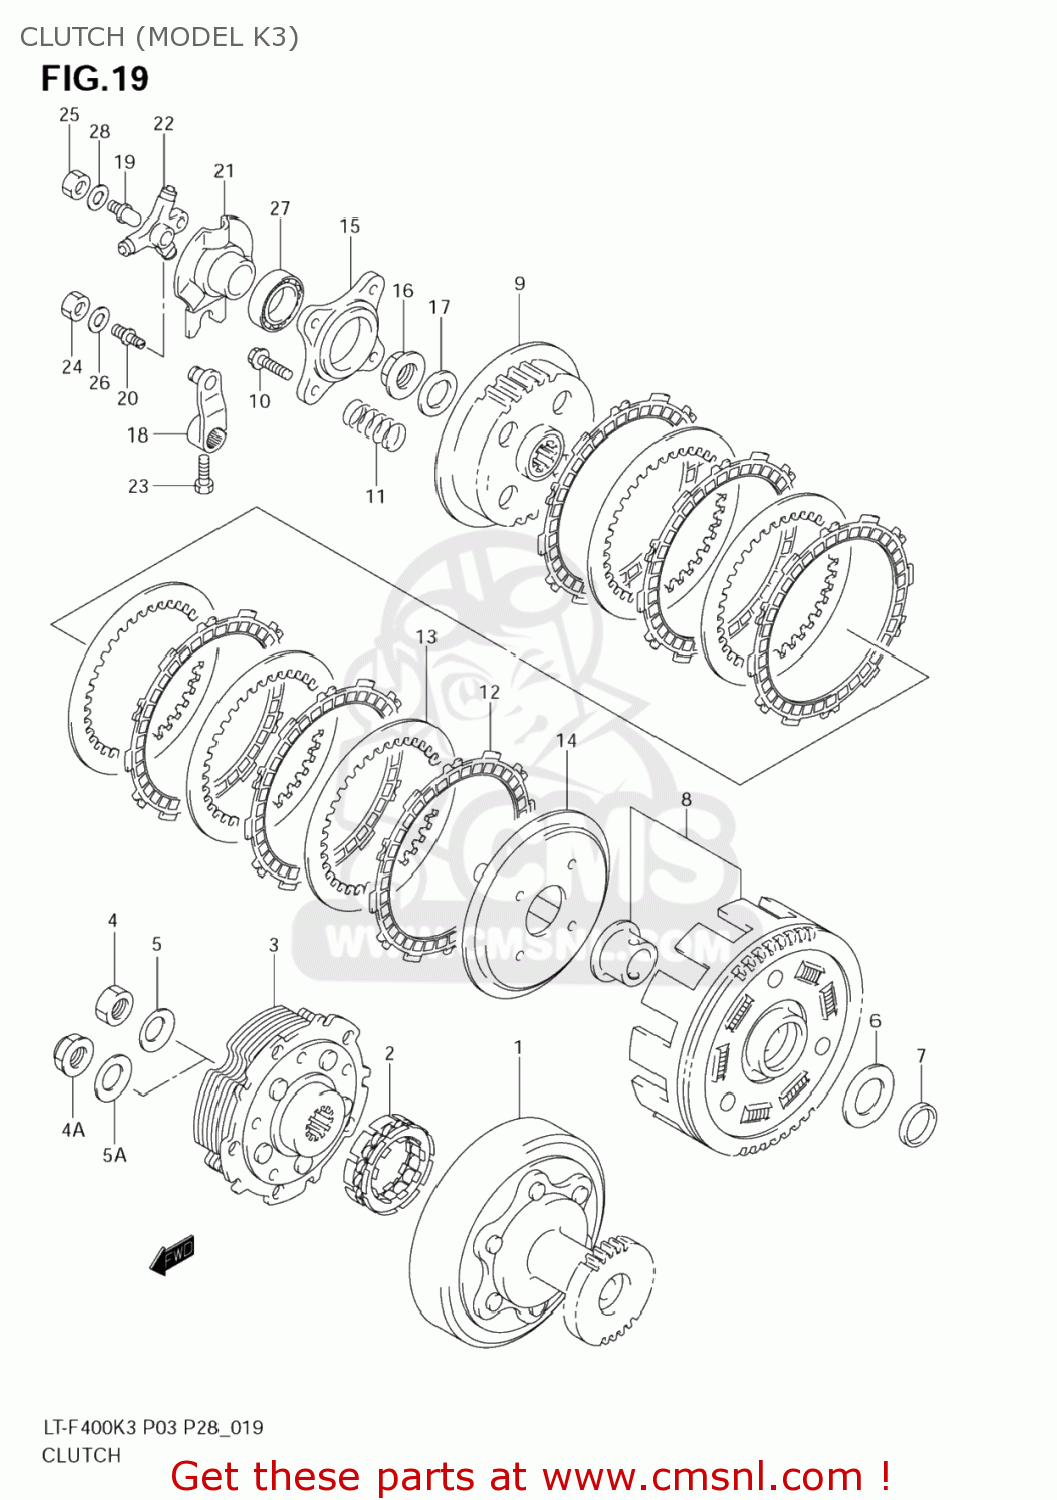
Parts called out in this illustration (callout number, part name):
1	HOUSING,STARTER CLUTCH
2	CLUTCH,PRIMARY DRIVE ONE WAY
3	SHOE,STARTER CLUTCH (NAS)
4	NUT
4A	NUT,STARTER CLUTCH SHOE
5	WASHER
5A	WASHER
6	SPACER(22X28X3.5)
7	WASHER
8	GEAR ASSY,PRI DRIVEN
9	HUB,CLUTCH SLEEVE
10	BOLT(6X25)
11	SPRING,CLUTCH
12	PLATE,CLUTCH DRIVE (NAS)
13	PLATE,CLUTCH DRIVEN (NAS)
14	DISC,CLUTCH PRESSURE
15	PLATE,CLUTCH RELEASE
16	NUT,CLUTCH SLEEVE HUB
17	WASHER
18	ARM,CLUTCH RELEASE
19	BOLT,CLUTCH RLSE ADJ NO.1
20	BOLT,CLUTCH RLSE ADJ NO.2
21	GUIDE,CL RELEASE ROLLER
22	ROLLER ASSY,CLUTCH RELEASE
23	BOLT
24	NUT
25	NUT (8MM)
26	WASHER(6.5X16X1.2)
27	BEARING
28	WASHER(8X20X1)
